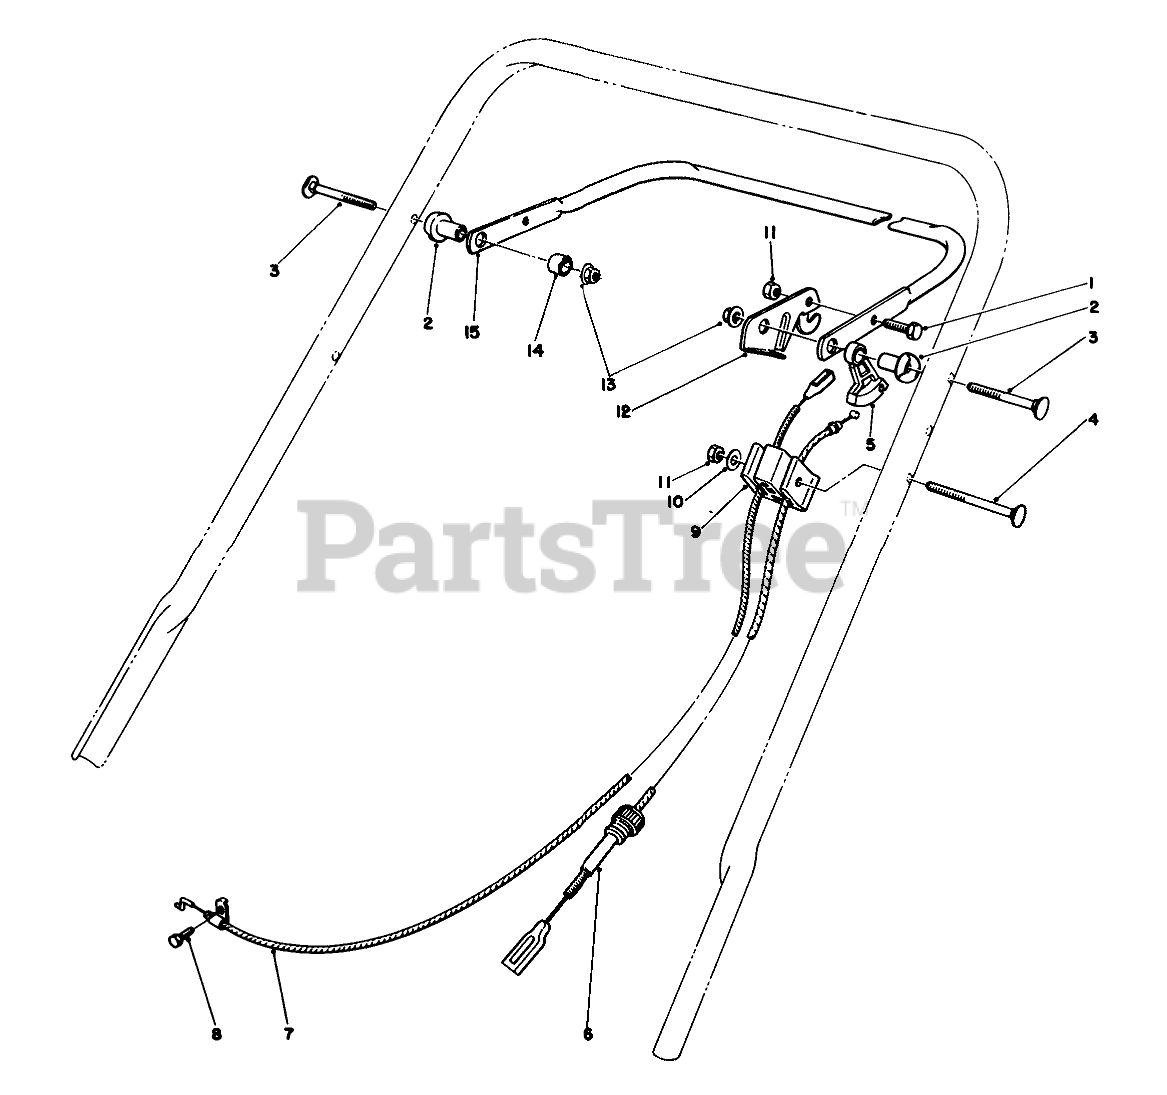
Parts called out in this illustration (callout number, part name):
1	SCREW-HH
2	SPACER-SUPPORT
3	5/16-18 X 2 HNDLE SCREW
4	HANDLE SCREW
5	LEVER-TRACTION
6	CABLE-TRACTION
7	BRAKE CABLE
8	SCREW-HH
9	SUPPORT-CABLE
10	WASHER-FLAT
11	NUT-LOCK, NI
12	LEVER-CONTROL
13	NUT-LOCK, NI
14	SPACER-NYLON
15	Bar-Control
